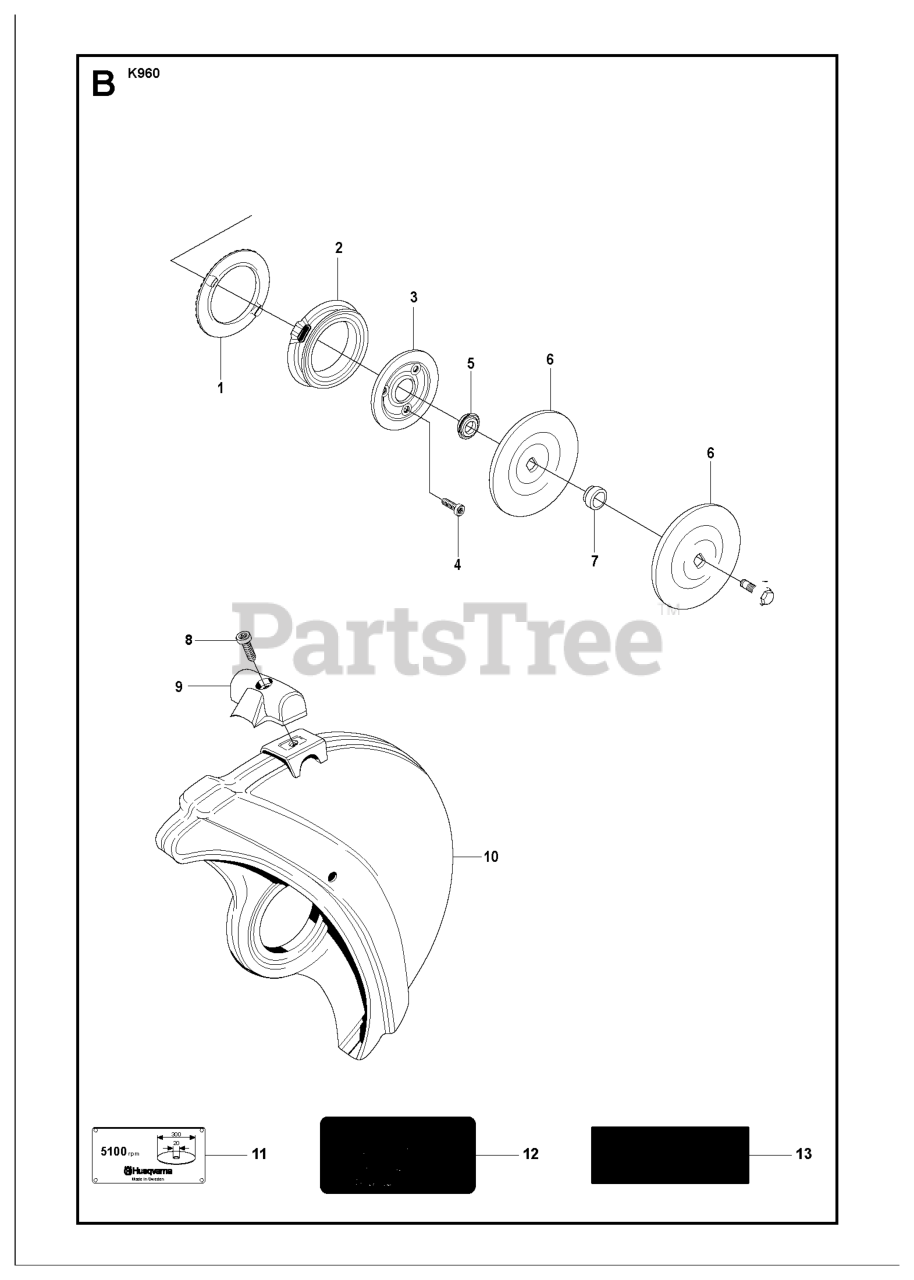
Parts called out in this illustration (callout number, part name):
4	SCREW ITXSCM
6	WASHER
7	BUSHING-30MM
7	BUSHING
8	SCREW.
10	WHEEL GUARD ASSY, 12" GREY
10	WHEEL GUARD ASSY
10	WHEEL GUARD ASSY, 16" GREY
11	Label
11	LABEL
12	ARBOR SIZE DECAL/25.4
12	ARBOR SIZE DECAL/20
13	ARBOR SIZE DECAL/20
13	ARBOR SIZE DECAL/25.4
